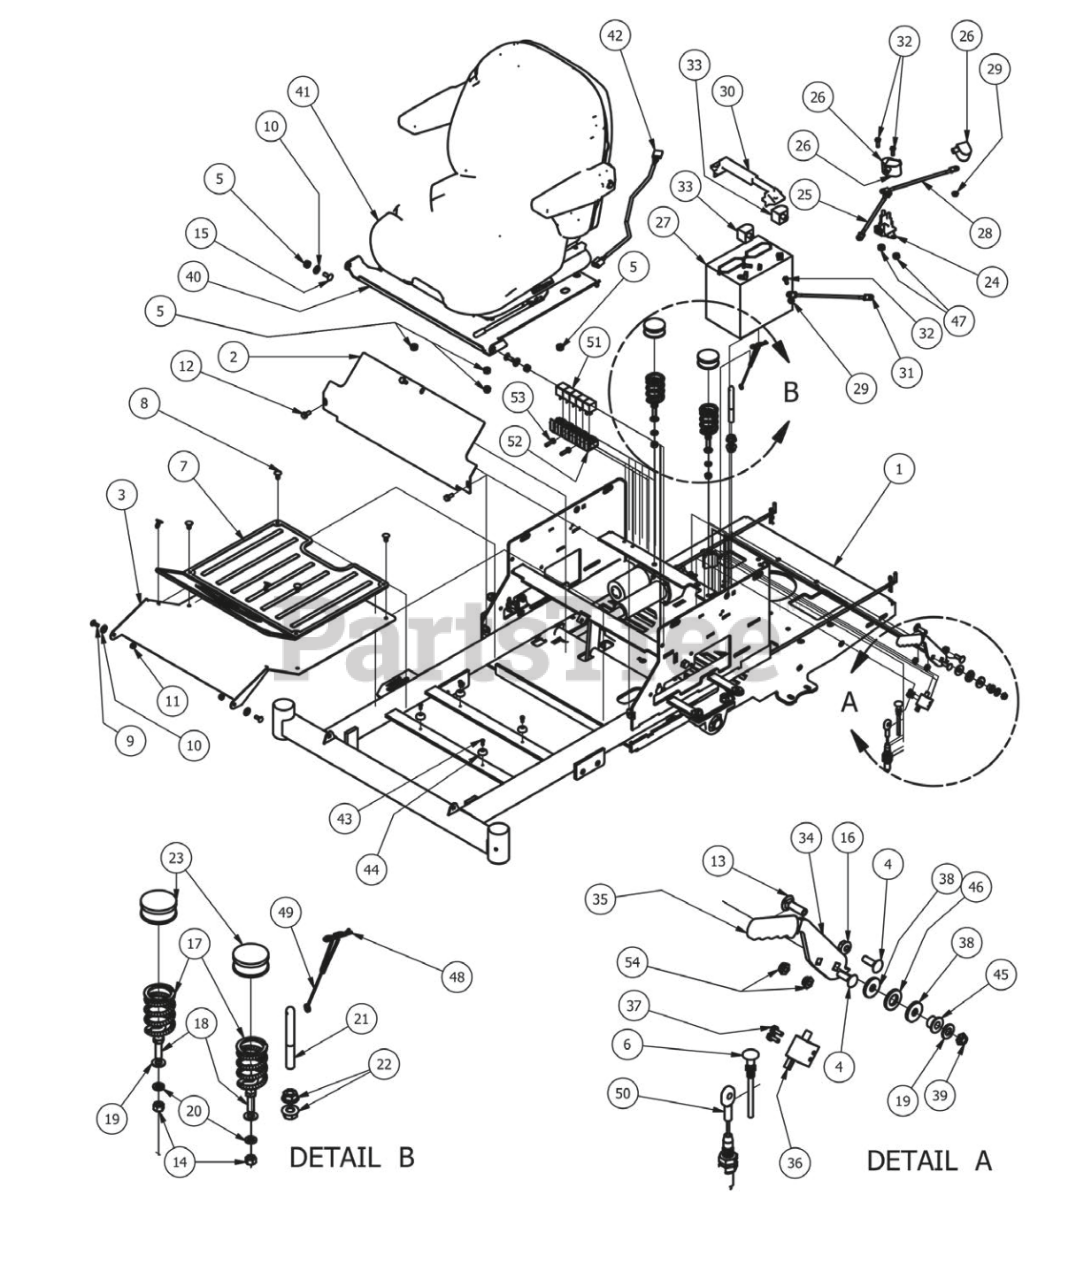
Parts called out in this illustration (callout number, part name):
1	ZT/CZT Frame 2013 Models
2	2013 ZT/CZT Cooler Cover
3	ZT/CZT FLOOR PANEL
4	5/16" x 1" Carriage Bolt
5	5/16-18 Nylon Flange Nut
7	Zt Floorboard Mat
8	Ratchet Fastener
9	1/4" x 3/4" Carriage Bolt
10	.360 ID Plastic Washer
11	1/4" Nylock Nut
12	|5/16 x 3/4 washer head type F screw
13	3/8" x 1 1/4" Carriage Bolt
14	3/8" Hex Nut
15	5/16" x 7/8" Carriage Bolt
16	5/16" Flange Nut
17	Seat Spring
18	3/8" x 1 1/4" Hex Bolt
19	3/8" Flat Washer
20	3/8" Lock Washer
21	Seat Braket Pin
22	1/2" Flange Nut
23	Spring Cap Cover
25	24 in red battery cable
27	ZT Battery
28	12 in red battery cable
29	1/4-20 Hex Flange Nuts Zinc w/Serrations
30	Hold Down Assembly
31	Starter to chassis cable
32	1/4-20 x 3/4 GR 5 Hex Bolts Zinc
33	Black Boot For ground cable
34	Brake Handle Cam Over
35	Rubber Brake Grip-cZT/ZT 2013
36	Safety Switch
37	12-24x 1/2 HWH Bolt
38	.390 ID Plastic Washer
39	3/8 Nylock Jam Nut 1/2 Nut
40	2013 ZT Seat Plate
41	Wise Seat ZT-WM1976
42	Seat Switch Adapter
43	| #10 x 1/2" Self Taping Screw
44	Button Bumper
45	Bronze Bushing SF-1220-8
46	.635 ID Plastic Washer
47	3/8" Fine Threaded Jam Nut
48	Seat latch pin
49	seat pin lanyard
50	Brake Cable
51	Relay Terminal
52	Harness-ZT Only 2008 and up
53	1/4 x 1 Hex Head tek screw
54	5/16-18 Nylock Jam Nut 1/2 Nut
